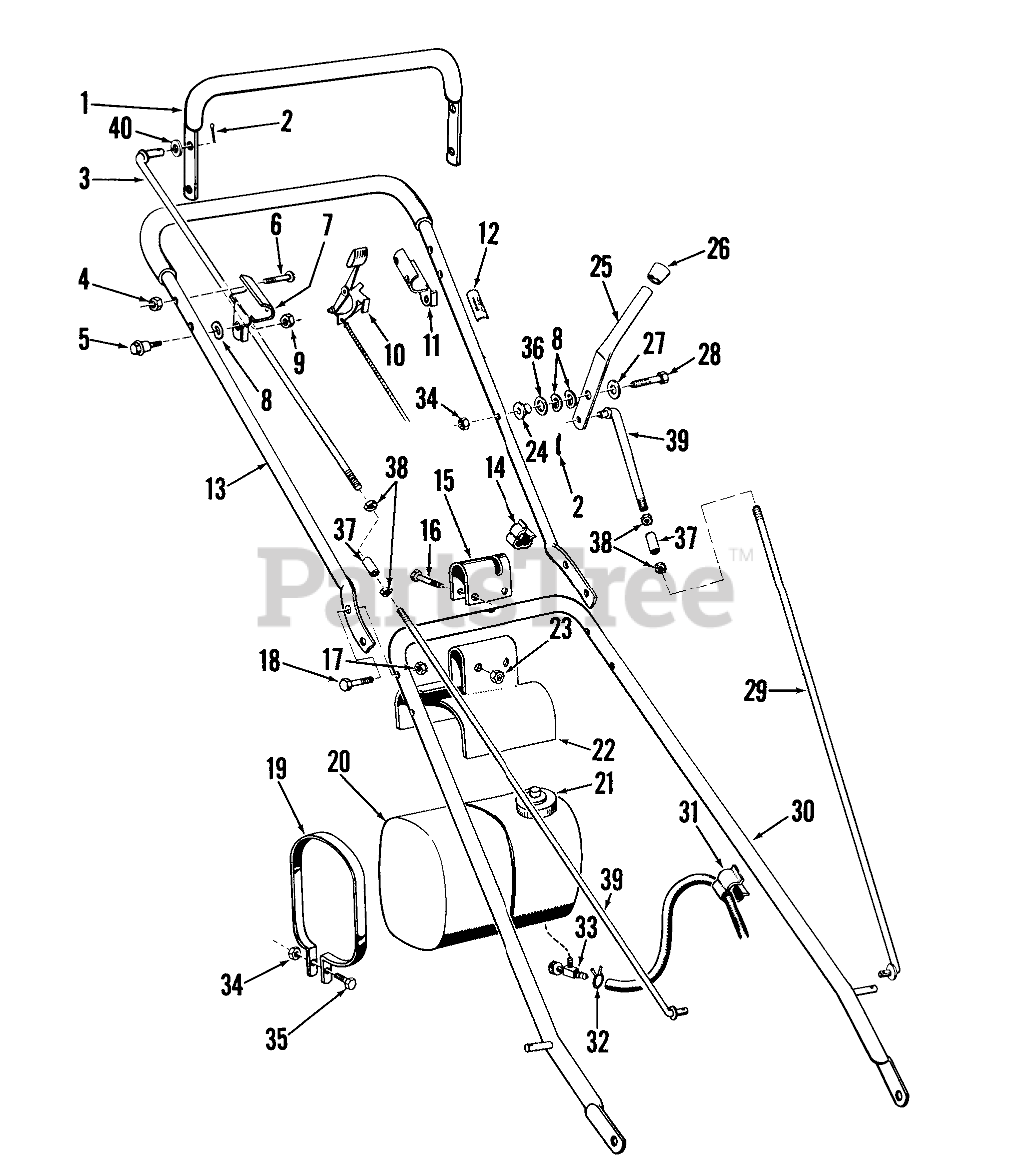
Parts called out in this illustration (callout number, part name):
1	Control Bail
2	PIN-COTTER
3	Control Rod
4	NUT-LOCK, NI
5	SCREW-SHOULDER
6	10-24X1-1/4 PAN HD MS
7	CONTROL BAIL BRACKET
8	WASHER-SPRING
9	NUT-LOCK, NI
10	Throttle Control
11	Bracket-Control Bail
12	Decal
13	Upper Handle Assembly
13	Upper Handle Assy.
14	Clamp
15	Clamp, Fuel Tank
16	SCREW-HH
17	NUT-LOCK, NI
18	SCREW-HH
19	TANK STRAP
20	Tank
22	FUEL TANK BRACKET
23	NUT-LOCK, NI
24	PIVOT
25	CUTTER HANDLE R
26	Button Plug
27	WASHER-FLAT
28	SCREW-HH
29	Cutter Link
30	Lower Handle Assy.
30	Lower Handle
31	CLAMP
32	Clamp
33	.125 ID SHUTOFF VALVE
34	NUT-LOCK, NI
35	SCREW-HH
36	WASHER-FLAT
37	CONTROL ROD SLEEVE
38	NUT-HEX
39	Control Rod, Lower
40	Spacer
